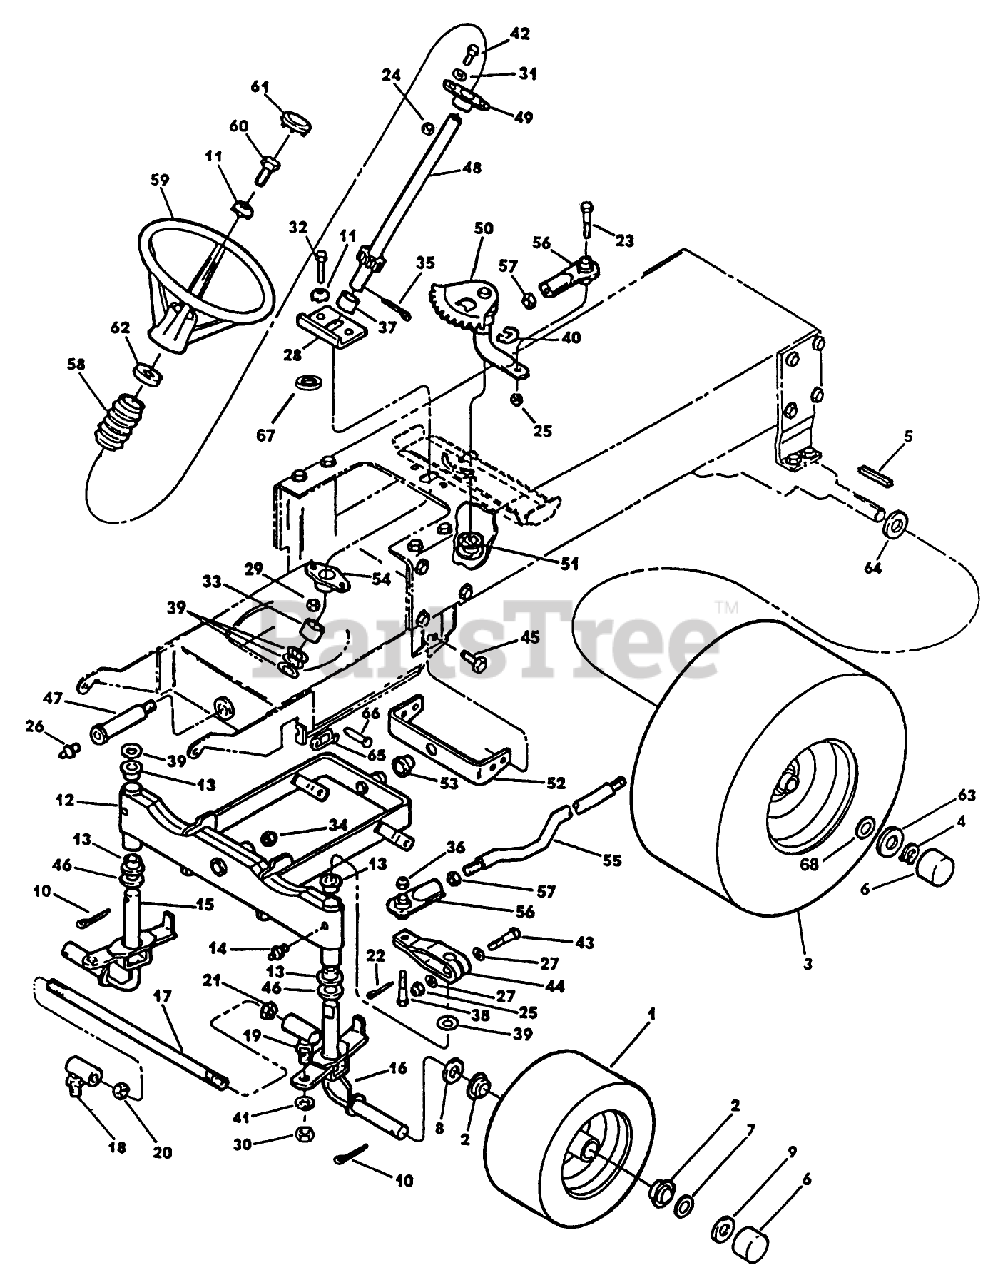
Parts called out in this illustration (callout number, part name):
5	KEY-SQUARE 1/4X1/4
9	WASHER
13	BEARING - BRONZE
17	ROD, STEER 1/2
18	BALL JOINT R.H.
19	BALL JOINT L.H.
24	NUT-LOCK, CONE
25	NUT-LOCKING
27	WASHER
29	NUT
32	SCREW
34	NUT-HEX
37	SPACER
39	SPACER
42	SCREW-HH
46	WASHER - THRUST
49	BEARING AY.
56	BALL JOINT
57	NUT-HEX
60	SCREW - HEX
68	WASHER - SPECIAL
